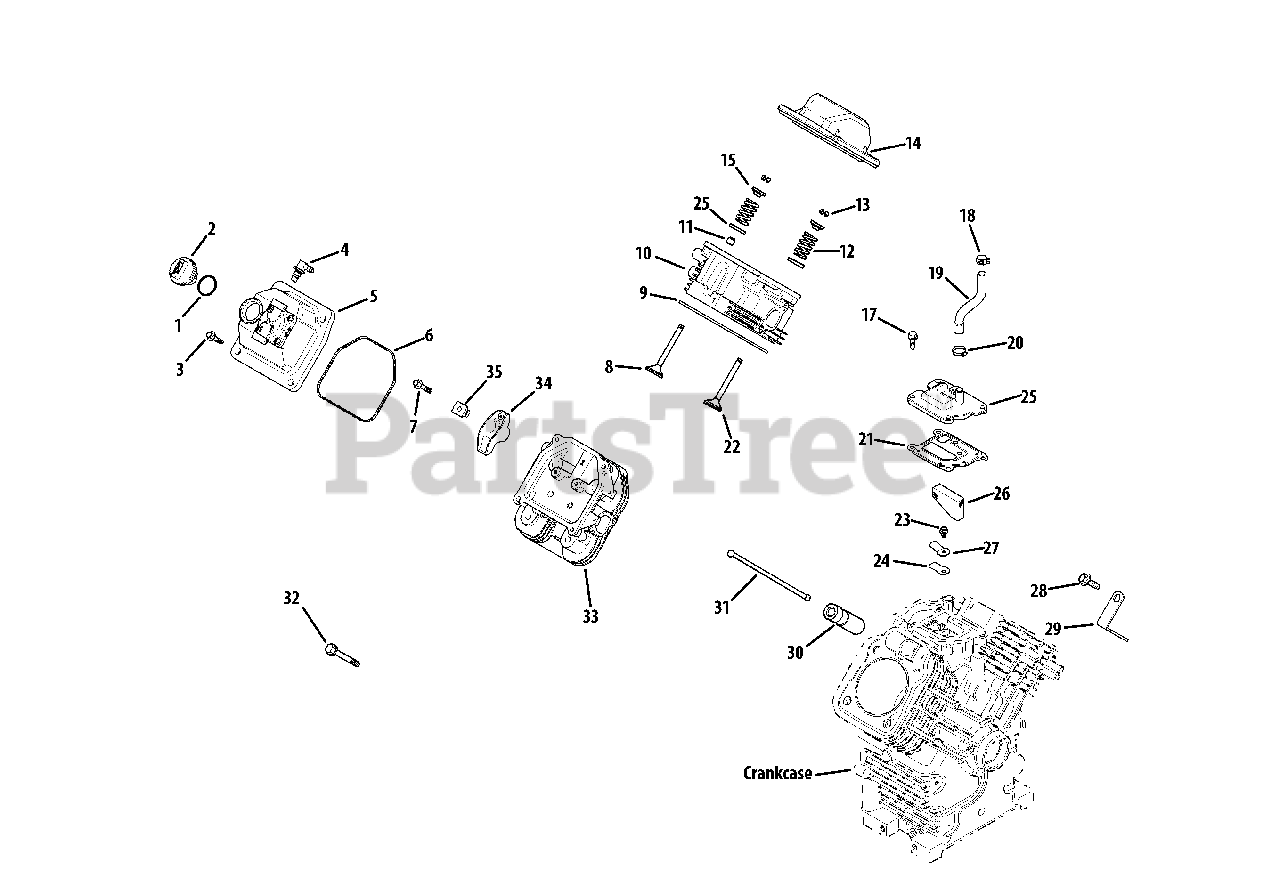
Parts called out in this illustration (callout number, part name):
2	Oil Fill Cap Assembly
3	Flange Screw, M6 x 1.0 x 30
4	90 Degree Fitting Kit
5	Valve Cover-Fuel Pump Kit
6	Vlave Cover O-Ring
7	Flange Screw, M6 x 1.0 x 34
8	Exhaust Valve (Std)
8	Exhaust Valve (.25)
9	Cylinder Head Gasket Kit (C17-22)
10	#1 Cylinder Head Assembly Kit
11	Valve Stem Seal
12	Valve Spring
13	Retainer Kit
14	Valve Cover-Plain Kit
15	Valve Spring Cap
16	Spring Retainer
17	Thread Forming Screw
18	Band Spring Hose Clamp
19	Breather Hose
20	Hose Clamp (KM)
21	Breather Gasket
22	Intake Valve (Std)
22	Intake Valve (.25)
23	Flange Thread Forming Screw,M5 x .8 x 10
24	Breather Reed
25	Breather Assembly Kit
26	Breather Filter
27	Reed Retainer
28	Thread Forming Screw
30	Hydraulic Valve Lifter
32	Flange Screw, M10 x 1.5 x 90
33	#2 Cylinder Head Assembly Kit
34	Valve Train Kit
35	Rocker Arm Pivot
